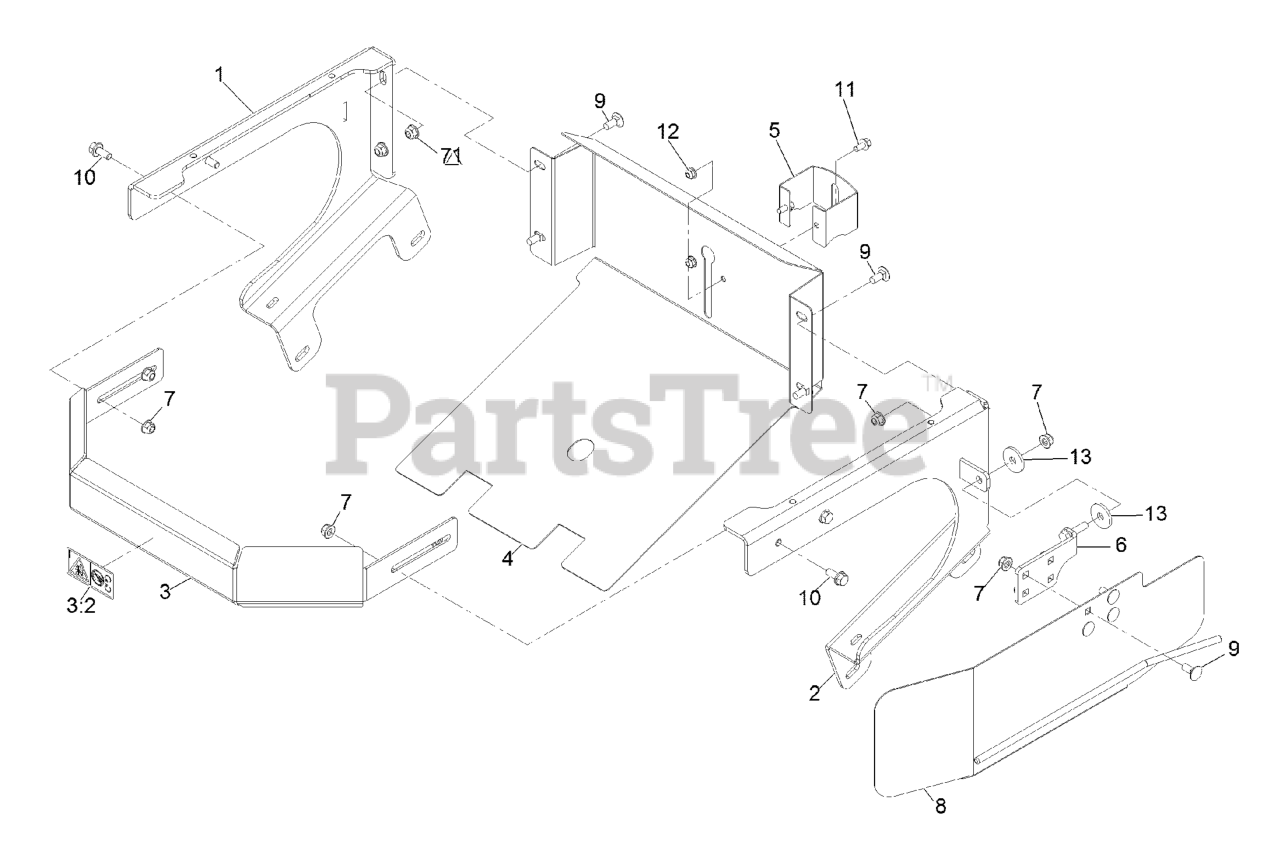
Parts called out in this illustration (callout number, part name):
1	FRAME-HOPPER, RH
2	FRAME-HOPPER, LH
3	BUMPER-FRONT
3:2	Decal-Dismemberment Hazard
4	BACKSHIELD, AE HOPPER
5	BRACKET-CABLE, HOPPER
6	MOUNT-DEFLECTOR
7	Nut-Hex Flange
8	DEFLECTOR-ZPLUG
9	SCREW-CARR
10	SCREW-HHF
11	SCREW-HHF
12	Nut-Hex Flange
13	WASHER
